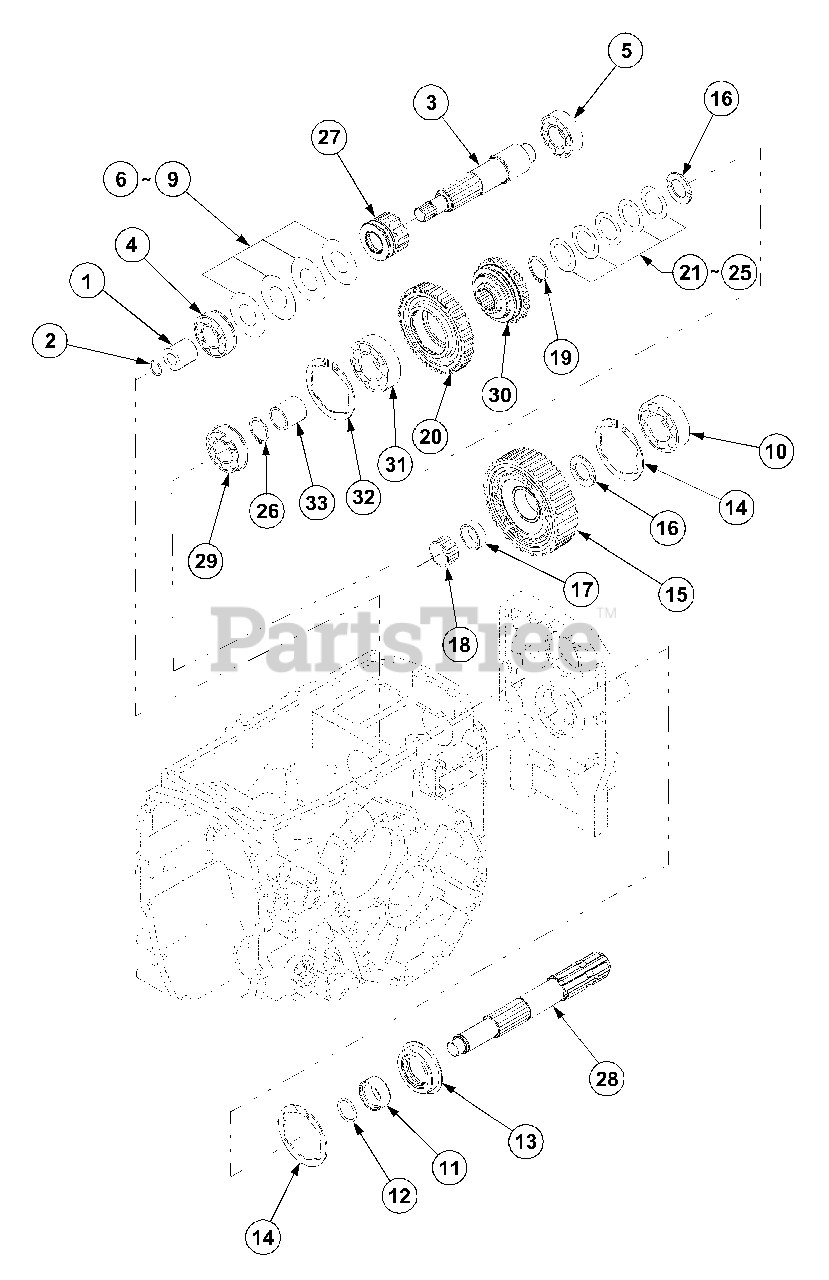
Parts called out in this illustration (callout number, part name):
3	Shaft,PTO Drive
13	Seal,Oil
18	Bearing,Needle
19	C-Ring
26	C-Ring
